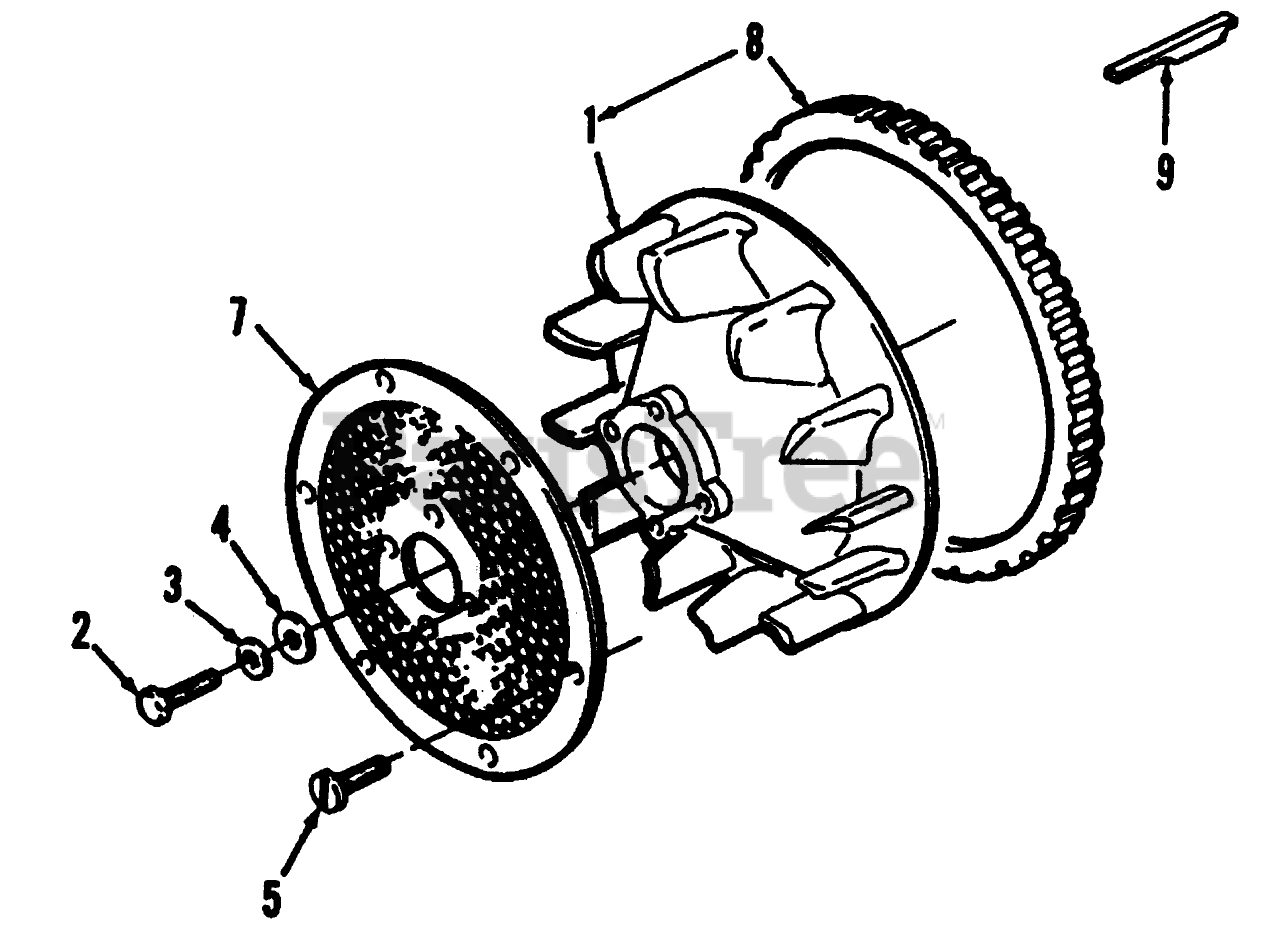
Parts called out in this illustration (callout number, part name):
3	WASHER-FLAT
4	WASHER-FLAT
7	SCREEN-AIR INLET
